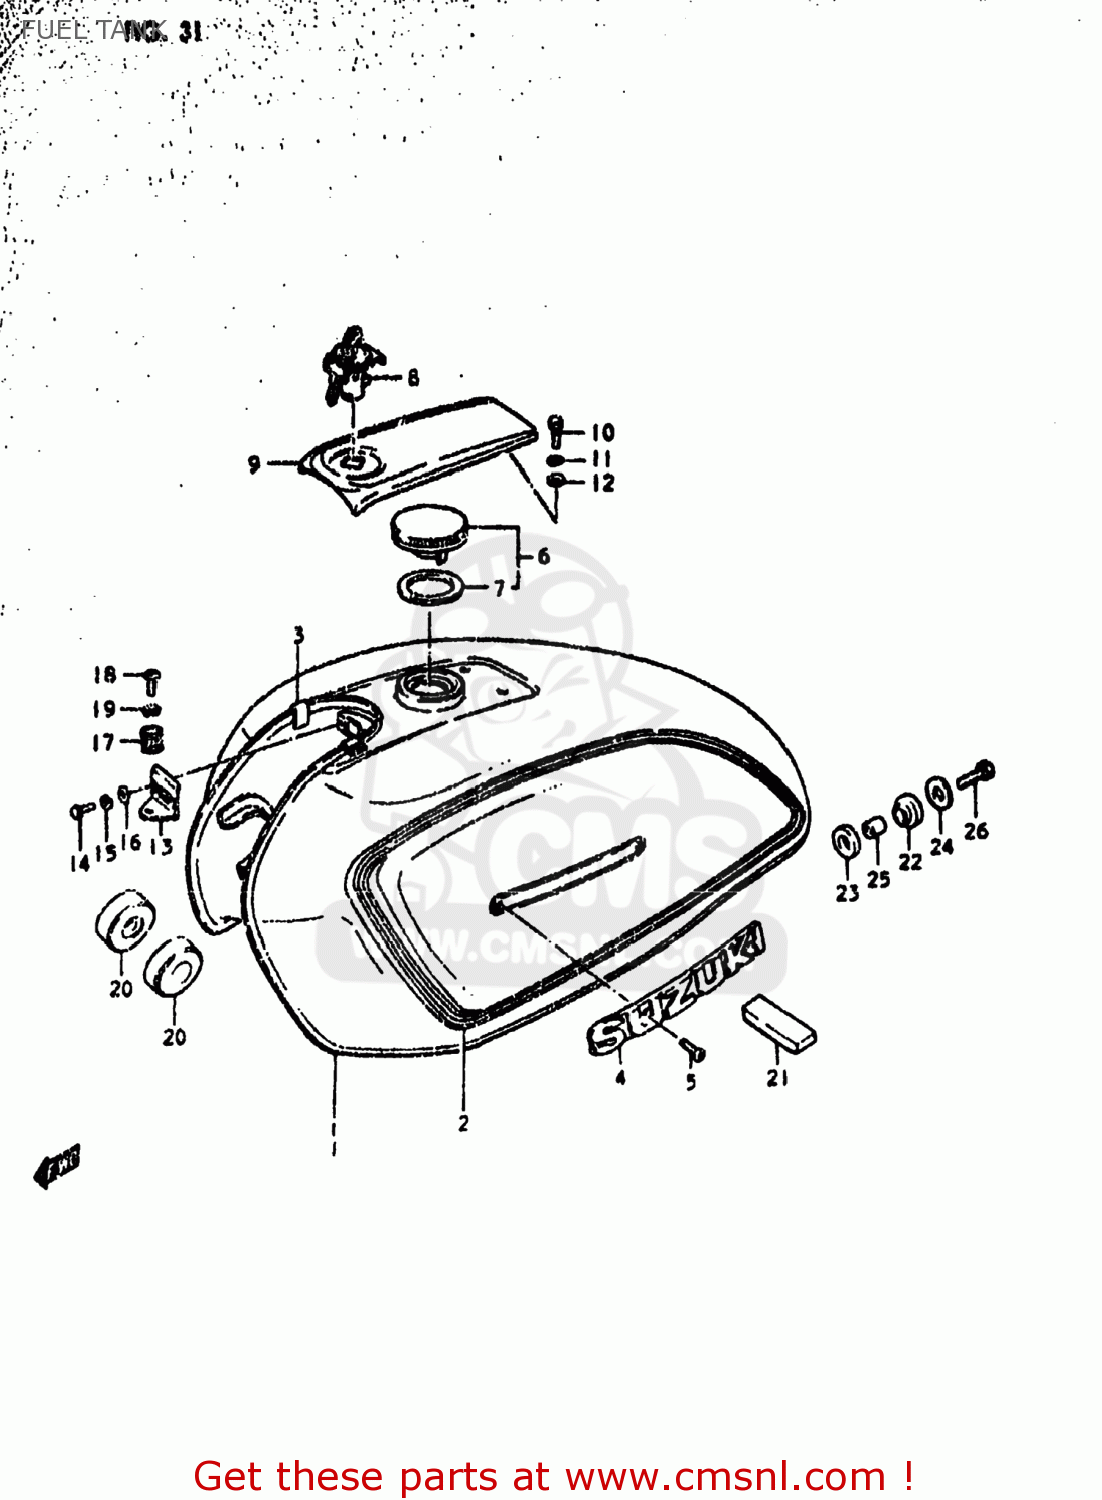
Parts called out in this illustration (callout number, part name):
1	TANK ASSEMBLY,FUEL
2	TAPE SET,FUEL TANK
3	CUSHION,FUEL TANK FR COVER
4	EMBLEM,FUEL TANK
5	SCREW 3X6
6	CAP ASSY,FUEL TANK FILLER
7	GASKET (NAS)
8	LOCK,FUEL TANK FR COVER
9	COVER,FUEL TANK,FRONT
10	BOLT
11	LOCK WASHER
12	WASHER
13	HOLDER,FUEL TANK FRONT COVER
14	BOLT
15	LOCK WASHER
16	WASHER
17	SPRING
18	SCREW
19	LOCK WASHER
20	CUSHION
21	CUSHION
22	CUSHION
23	CUSHION
24	WASHER (8.5X29X1.6)
25	SPACER(8.5X12X19)
26	BOLT (8X30)
